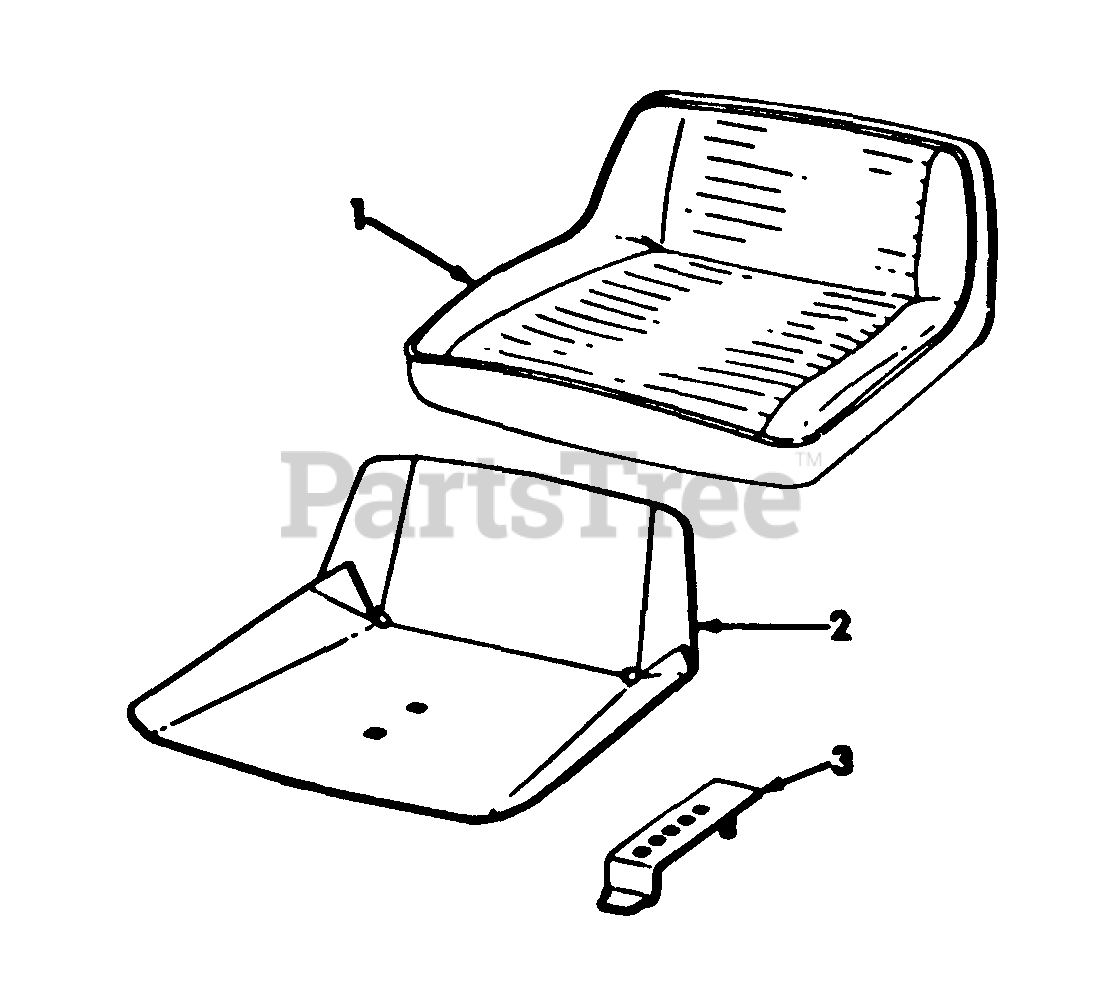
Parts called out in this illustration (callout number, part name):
1	SEAT, CUSHION
2	PACKAGE, SEAT SERVICE
3	SUPPORT ASSY, SEAT ADJ
